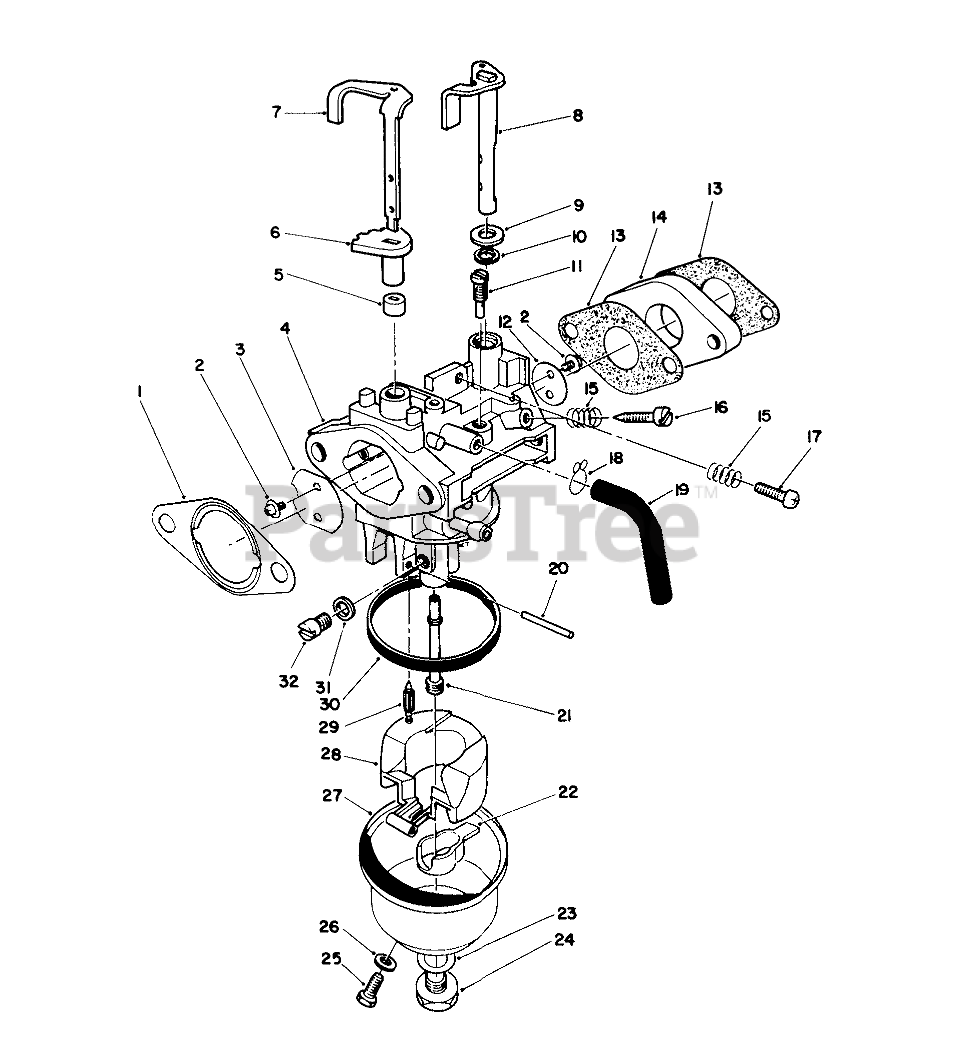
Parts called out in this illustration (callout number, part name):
1	GASKET F/W ENGINE
2	Screw
3	VALVE
4	Body-Carburetor
5	LOWER CHOKE RING
6	UPPER CHOKE RING
7	Shaft-Choke Valve
8	SHAFT
9	WASHER
10	Seal-Throttle Shaft
11	JET - PILOT
12	VALVE
13	GASKET INTAKE
14	INSULATOR - CARB.
15	SPRING-PILOT SCREW
16	ADJUSTER
17	SCREW
18	CLAMP
20	Pin
21	NOZZLE - MAIN
22	SPACER
23	GASKET
24	SCREW
25	SCREW
26	GASKET
28	FLOAT
29	NEEDLE
30	FLOAT BOWL GASKET
31	SPACER
32	JET-HIGH ALTITUDE
